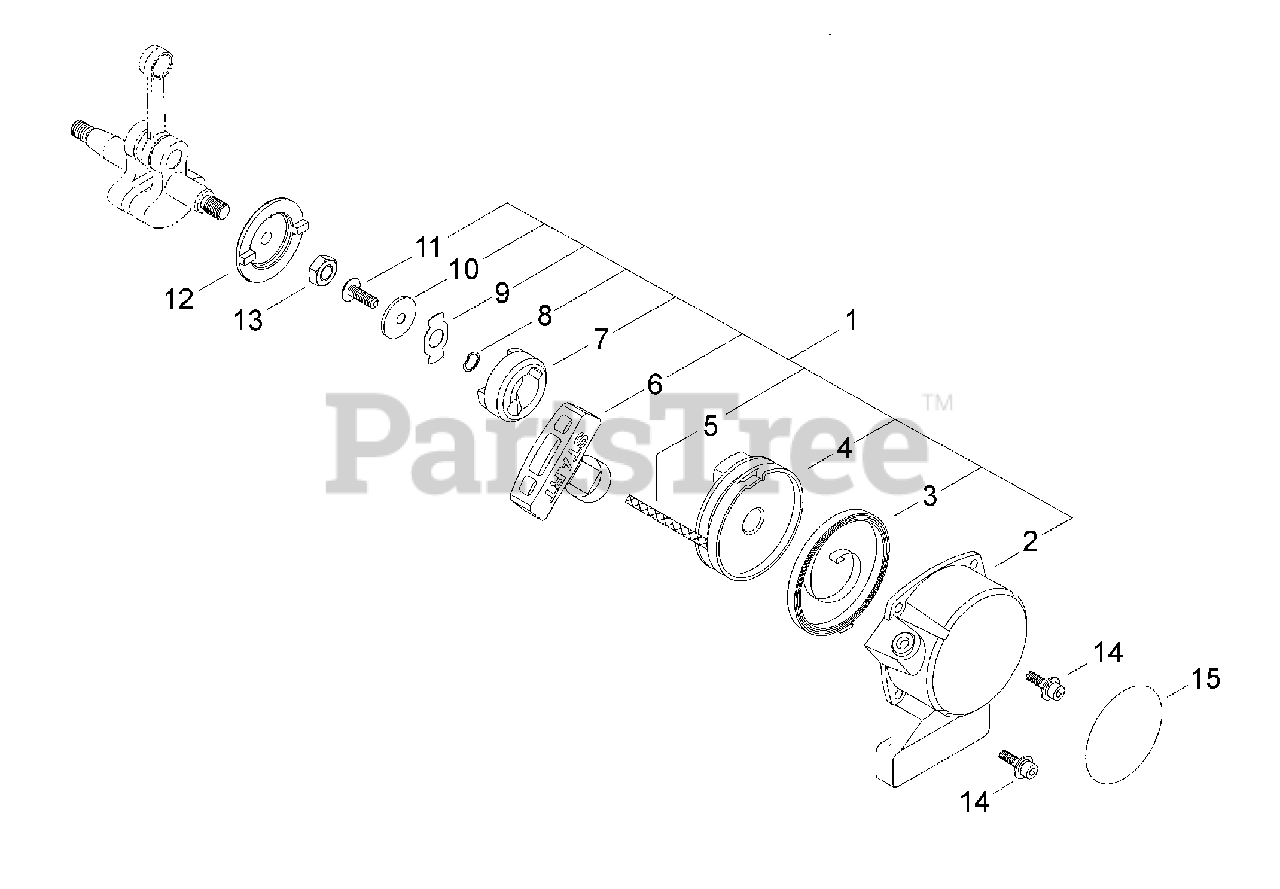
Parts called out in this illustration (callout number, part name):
1	STARTER ASSY
2	CASE, STARTER
3	SPRING, REWIND
4	REEL, ROPE
5	ROPE, STARTER
6	GRIP, STARTER
7	PAWL, STARTER
8	WASHER - SPRING
9	RETAINER
10	WASHER - 5
11	SCREW - 5
12	PAWL
13	NUT - 8
14	SCREW - 4X16
15	LABEL - C4
